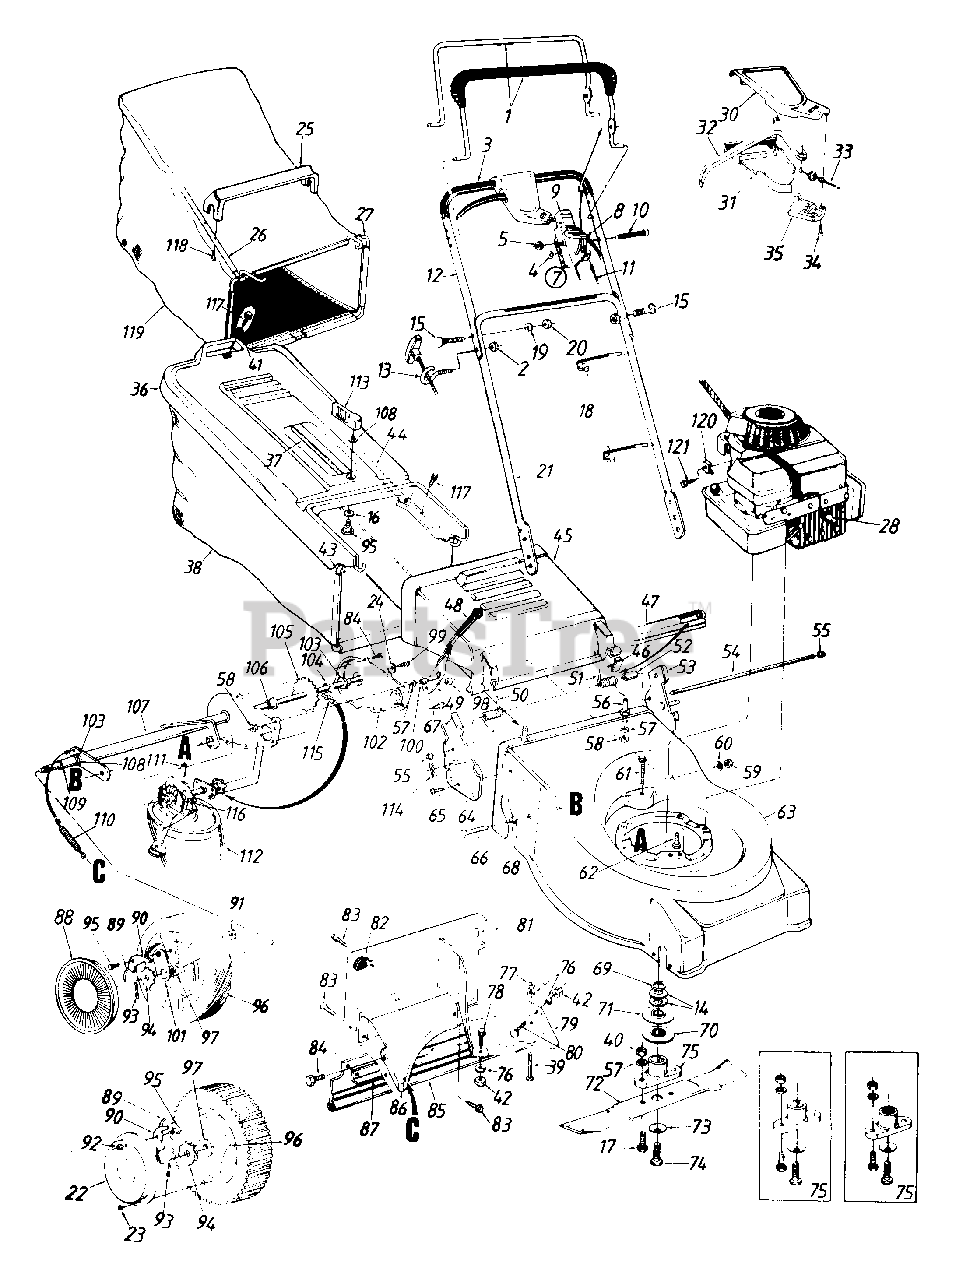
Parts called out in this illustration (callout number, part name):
1	Std. Control Handle
2	Hex Lock Nut 1/4-20 Thd.
3	Foam Grip
4	Spr. Wash..66" I.D.
5	Hex L-Nut 1/4-20 Thd.
6	Throttle Cable - 55" (B&S)
6	Throttle Cable - 45" (Tecumseh)
7	Throttle Box Comp.
8	Throttle Lever
9	Throttle Body
10	Oval C-Sunk Scr.
11	Control Cable - 40.5" (B&S)
11	Control Cable - 55" (Tecumseh)
12	Upper Handle
13	Rope Guide
14	Bell-Wash. 7/8" I.D.
14	Bell-Wash. 1.01" I.D.
15	Curved Carriage Bolt 5/16-18 x 1.38" Lg.
16	Bowed Washer
17	Hex Bolt 3/8-24 x 1" Lg.
18	Cable Tie
19	L-Wash. 5/16" I.D.
20	Hex Nut 5/16-18 Thd.
22	Hub Cap (Optional)
23	Pan Hd. Tap Scr. #12 x .50" Lg.
24	Bell-Wash..265" I.D. x .75"
25	Bag Handle
26	Rear Catcher Frame
27	Front Catcher Frame
28	Spark Plug Boot (Optional)
30	Control Cover Half - Upper
31	Control Cover Half - Lower
32	Control Lever
33	Drive Cable - 51" Lg.
34	Flat C-Sunk Hd. Tap Scr. #10 x .75" Lg.
35	Cable Mtg. Cap
36	Hardtop Bag Cover
37	Hardtop Handle
38	Grass Bag
39	Truss Mach. Scr. 1/4-20 x 1.0" Lg.
40	Hex Nut 3/8-24 Thd.
42	Hex Nut 1/4-20 Thd.
43	Front Catcher Frame
44	Rear Catcher Frame
45	Chute Deflector
46	Deflector Plug
47	Seal - Extrusion
49	Spring Lever
50	Torsion Spring - R.H.
51	Torsion Spring - L.H.
52	Spacer 255" I.D.
53	Handle Brkt. Ass'y.- L.H.
54	Hinge Pin 17.75" Lg.
55	Cap Speed Nut
56	Shld. Pin 3/8-24 x 1.43" Lg.
57	L-Wash. 3/8" I.D.
58	Hex Jam Nut 3/8-24 Thd.
59	Hex L-Nut 3/8-24 Thd.
60	Bell-Wash..38" I.D. x .88"
61	Hex Wash. Hd. Tap Scr. 1/4-20 x 1.5" Lg.
62	Hex L-Wash. Hd. Scr. 3/8-16 x 1" Lg.
65	Hex L-Wash. Hd. AB-Tap Scr. 1/4 x .62" Lg.
66	Hex Wash. Hd. Tap Scr. 3/8-16 x .75" Lg.
67	Hex Wash. Hd. Tap Scr. 1/4-20 x .5" Lg.
68	Spacer 383" I.D.
69	Crankshaft Spacer
70	Pulley Half - Lower
71	Pulley Half - Upper
71	Pulley Half - 2 Req'd.
72	21" Blade
73	Bell-Wash..39" I.D.
73	Bell-Wash..46" I.D.
74	Hex Bolt 3/8-24 x 1.5" Lg.
74	Hex Bolt 7/16-20 x 1.5" Lg.
75	Blade Adapter Kit
76	L-Wash. 1/4" I.D.
77	Hex Jam Nut 1/4-20 Thd.
78	Hex Bolt 1/4-20 x .85" Lg.
79	Rear Belt Baffle
80	Carr. Bolt 1/4-20 x .50" Lg.
83	Torx Mach. AB-Tap Scr. 1/4 x 62" Lg
84	Hex B-Tap Scr. 1/4 x .38" Lg.
85	Rear Flap
86	Rear Chute Baffle
88	Hub Cap Beige (5-1/2" Dia.)
88	Hub Cap Gray (3-1/2" Dia.)
88	Hub Cap Black (1-1/2" Dia.)
88	Hub Cap Red (1-3/8" Dia.)
89	Plastic Spring
90	Pawl .345" I.D.
91	Weld Top L-Nut 1/4-20 Thd. 62" Lg.
92	Hex Ins. L-Nut 1/4-20 Thd.
93	Cotter Pin 1/8" Dia.
94	Ratchet Wheel 1.62" O.D.
95	Shld. Bolt .342" Dia. x .268"
96	Wheel Ass'y. Comp.- Rear
96	8" x 1.75" Bar Tread
96	8" x 1.75" "T" Tread
96	8" x 2" "S" Wave (Silver)
96	8" x 2" "S" Wave (Beige)
97	Bearing 1/2" I.D.
97	1/2" I.D. Ball Brg. (2 Req'd.)
97	1/2" I.D. Sleeve Brg.
98	Shld. Spacer .50" Dia.
99	Hex Bolt 1/4-20 x .62" Lg. (Gr 5)
100	Shld. Pin 3/8-24 x 1.43" Lg.
101	Pawl Plate
104	Fl-Wash..531" I.D. x .93"
105	Rear Axle Ass'y.
106	Hex Flange Bearing
109	Spacer 513" I.D.
110	Extension Spring 3.8" Lg.
111	Spacer.325" I.D.
112	V-Belt
113	Grass Catcher Locking Knob
114	Internal Cotter Pin 5/16" Dia.
115	#48 Chain .50" Pitch x 30 Links
116	Transmission Comp.
117	Hex L-Wash. H.D. AB-Tap Scr. 1/4 x .62" Lg.
118	Hex AB-Tap Scr. #12 x 1.25" Lg.
119	Grass Bag
120	Cable Clamp (B&S)
121	Hex Self-Tap Scr. #10-32 x 62" Lg. (B&S)
